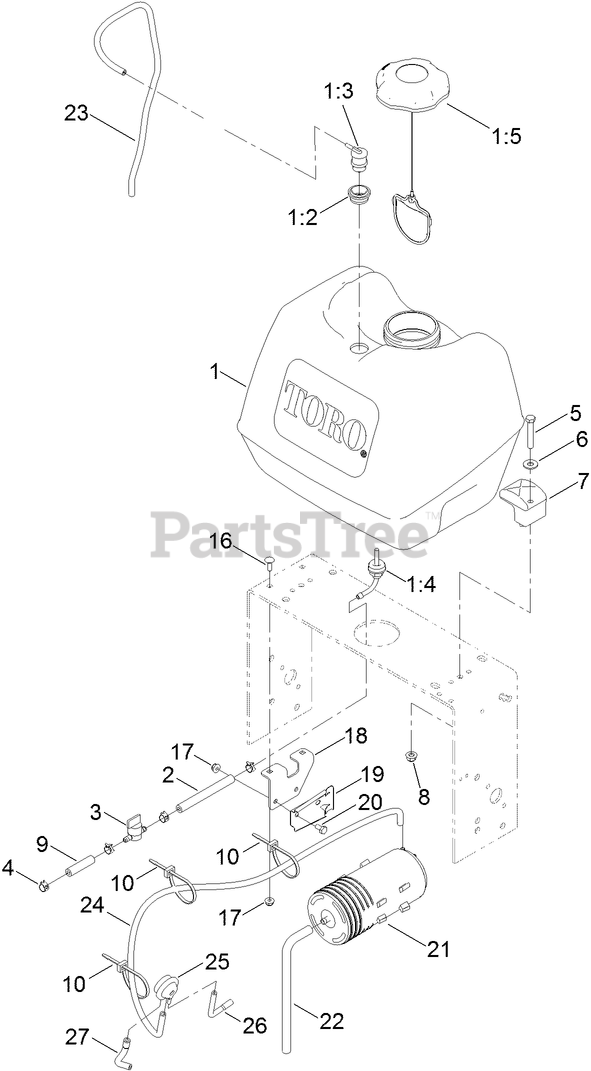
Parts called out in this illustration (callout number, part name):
1	FUEL TANK ASM
1:2	GROMMET
1:3	VALVE-VENT, FUEL
1:4	FITTING-FUEL, BULKHEAD
1:5	CAP-FUEL, RATCHETING
2	HOSE-FUEL
3	VALVE-FUEL
4	CLAMP-HOSE
5	SCREW-HH
6	WASHER-FLAT
8	NUT-HF, NI
9	HOSE-FUEL
10	TIE-CABLE
16	BOLT-CARR
17	NUT-HF
18	BRACKET-CANISTER, CARBON
19	BRACKET-CANISTER, CARBON
20	SCREW-HH
21	CANISTER-CARBON, 800CC
22	HOSE-VENT, CANISTER
23	HOSE-VENT
24	HOSE-VENT, FORMED
25	VALVE-CONTROL, VACUUM
26	HOSE-VENT, FORMED
27	HOSE-VENT, FORMED
